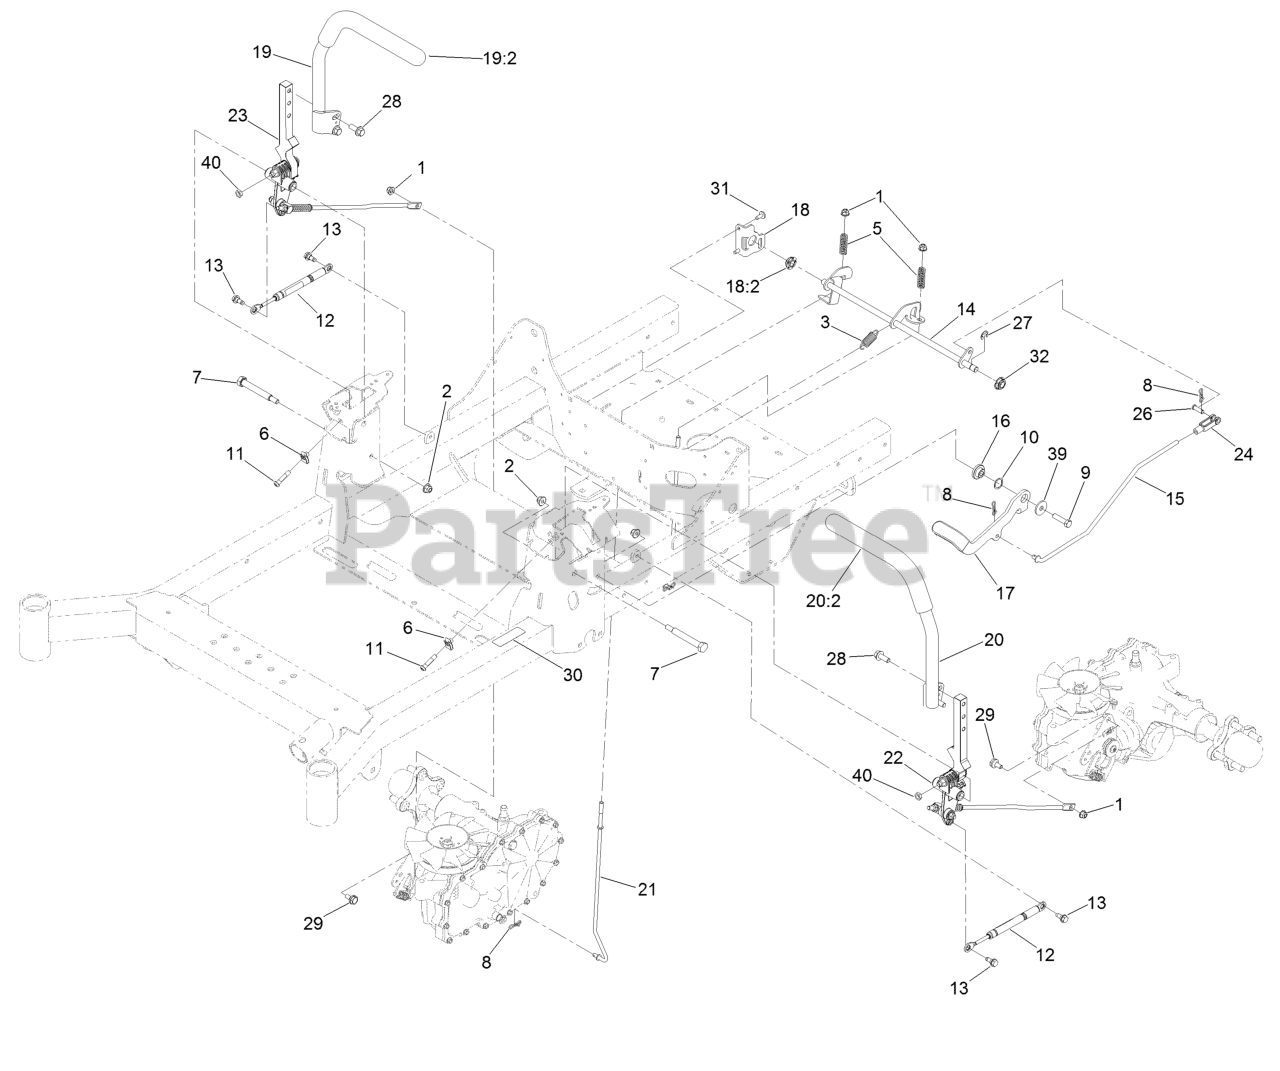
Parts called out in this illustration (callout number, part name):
1	Nut-HF, NI
2	Nut-HF, NI
3	Spring-Extension
5	Spring-Compression
7	Bolt-Pivot
8	Pin-Cotter, Locking
9	Screw-HH
10	Washer-Wave
11	Screw-HSBH
13	Screw-Shoulder
14	Shaft-Brake
15	Linkage-Brake, Upper
16	Pivot-Flange
17	Lever-Brake (With Grip)
18	Bracket-Brake
18:2	Bearing-Spherical
19	RH Control Handle ASM
20	LH Control Handle ASM
21	Linkage-Brake, Lower
22	LH Motion Control ASM
23	RH Motion Control ASM
24	Yoke-Adjustable
26	Pin-Clevis
27	Ring-Retaining, External
28	Screw-HHF
29	Bolt-Shoulder
30	Decal-Brake, Parking
31	Screw-Torx
32	Bearing-Spherical
39	Washer
40	Nut-Jam
